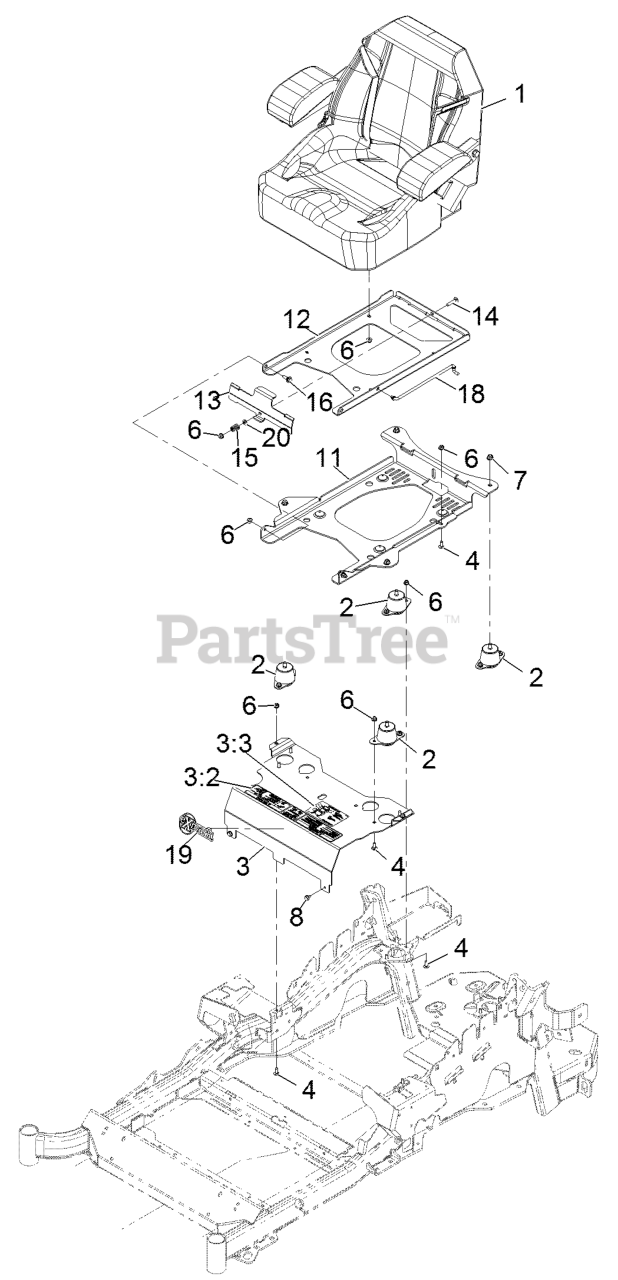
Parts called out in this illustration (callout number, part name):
2	ISOLATOR-SEAT
3	MOUNT-SEAT
3:2	DECAL-CONSOLE
3:3	DECAL-SERVICE AID
4	SCREW-CARR
6	NUT-HF, NI
7	NUT-HF, NI
11	PLATE-TILT, SEAT SUPPORT
12	PLATE-FRAME, SEAT
13	PLATE-LATCH, SEAT
14	BOLT-CARR
15	SPRING-COMPRESSION
16	SCREW-SHOULDER
18	ROD-PROP
20	WASHER-PLAIN
